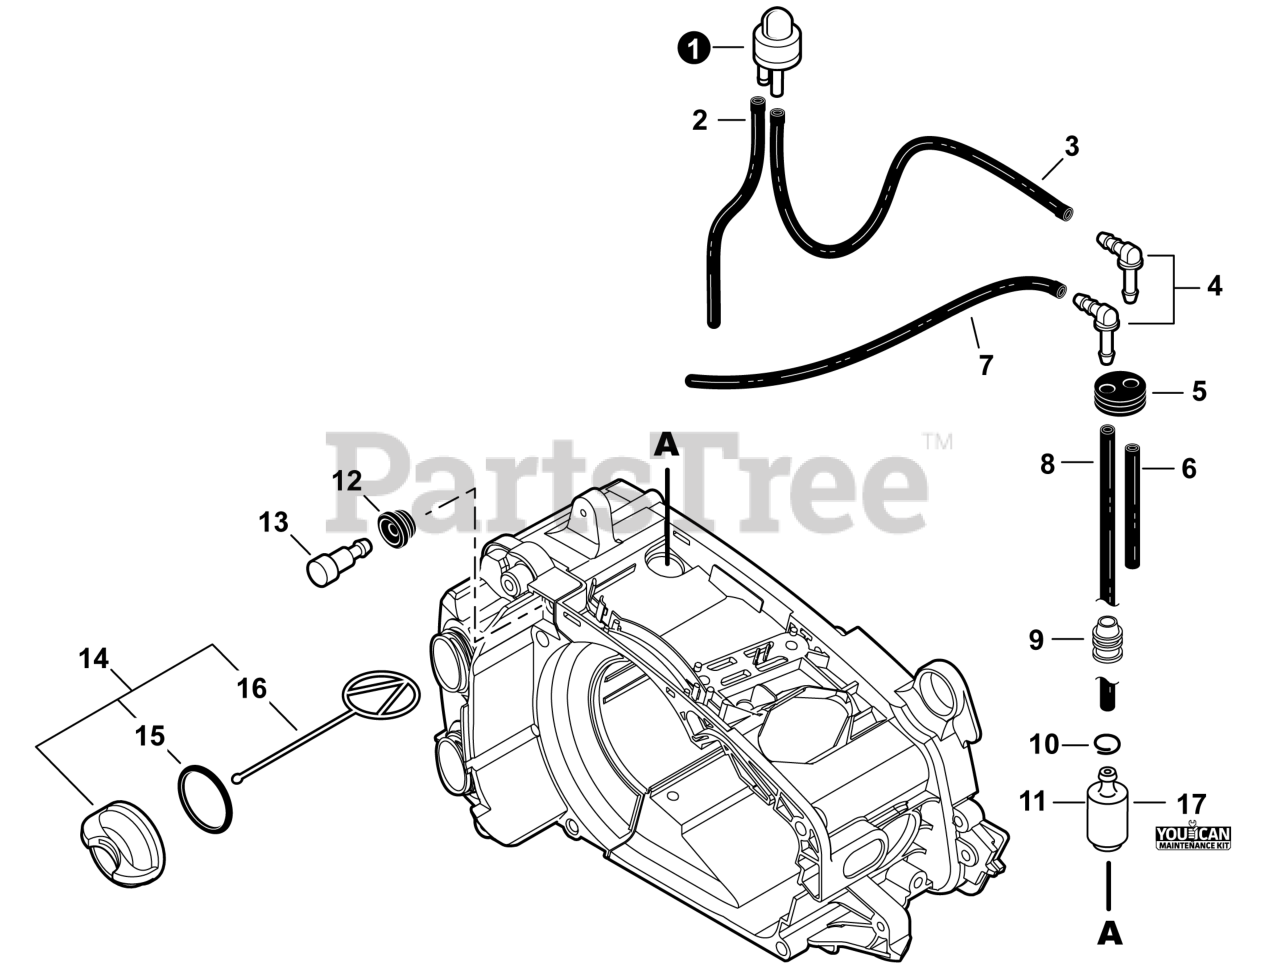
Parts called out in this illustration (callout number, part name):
1	BULB, PURGE
2	PIPE 2.4x5x180 - BLACK
3	PIPE 2.4x5x400 - BLACK
4	CONNECTOR, PIPE
5	GROMMET, FUEL
6	PIPE 2.4x5x15 - BLACK
7	PIPE 3x5x265 - BLACK
8	PIPE 3x5x140 - BLACK
11	FILTER, FUEL
12	GROMMET, FUEL
13	VENT ASSY
14	CAP ASSY, FUEL - ORANGE
16	CONNECTOR, CAP L= 60 MM
17	TUNE-UP KIT - YOUCANT
